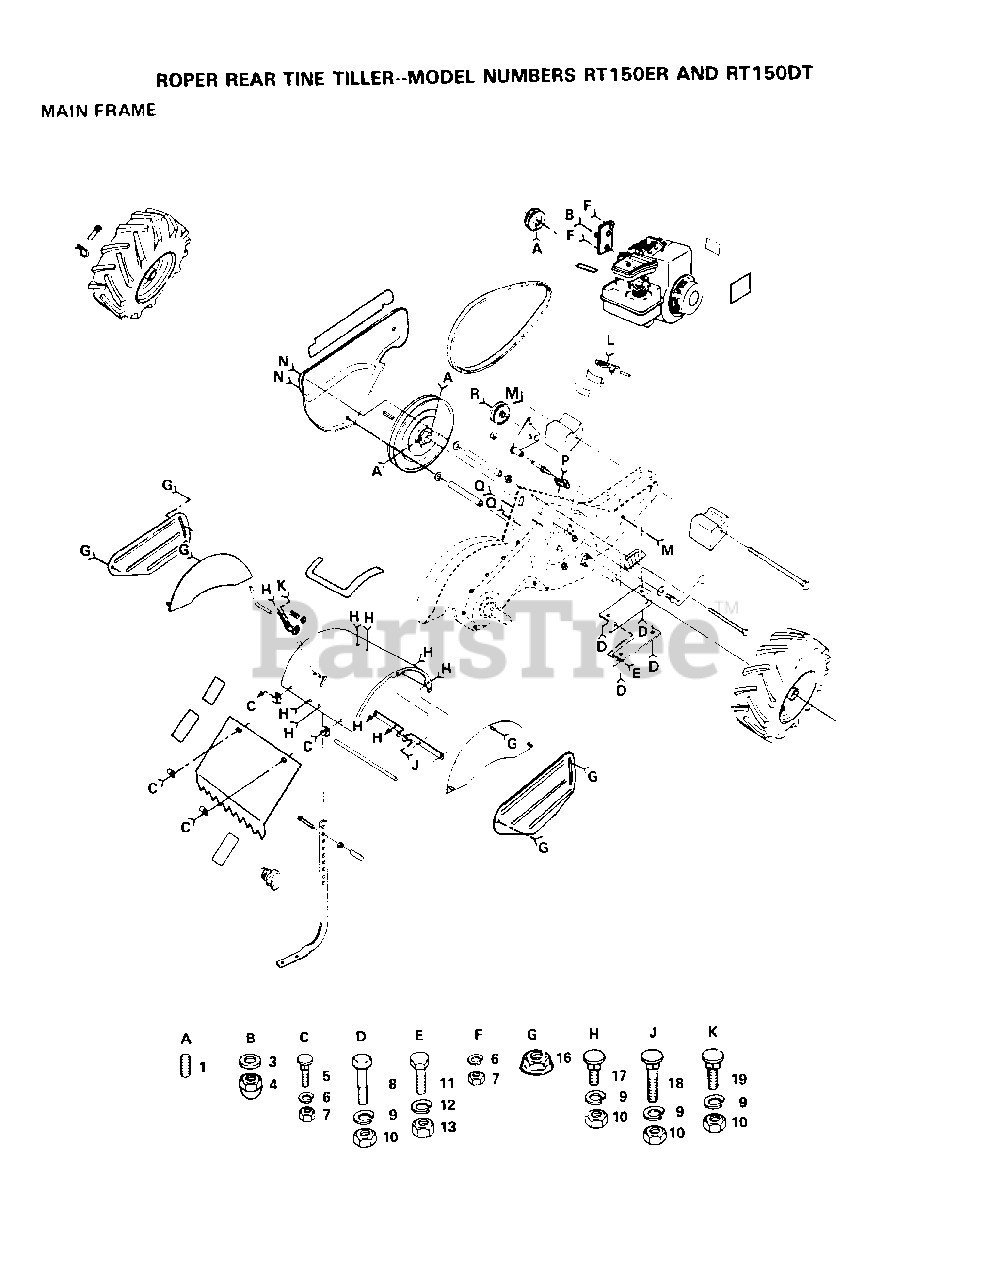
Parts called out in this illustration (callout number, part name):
1	SET SCREW
3	WASHER
4	NUT TI
5	BOLT
6	LOCKWASHER
8	BOLT.HEX.5/16-1.5
9	LOCKWASHER
10	NUT.HEX.5/16-18
11	BOLT
12	LOCKWASHER
13	NUT.HEX.3/8-16UNC
16	NUT
17	BOLT
18	BOLT CRT
19	BOLT
